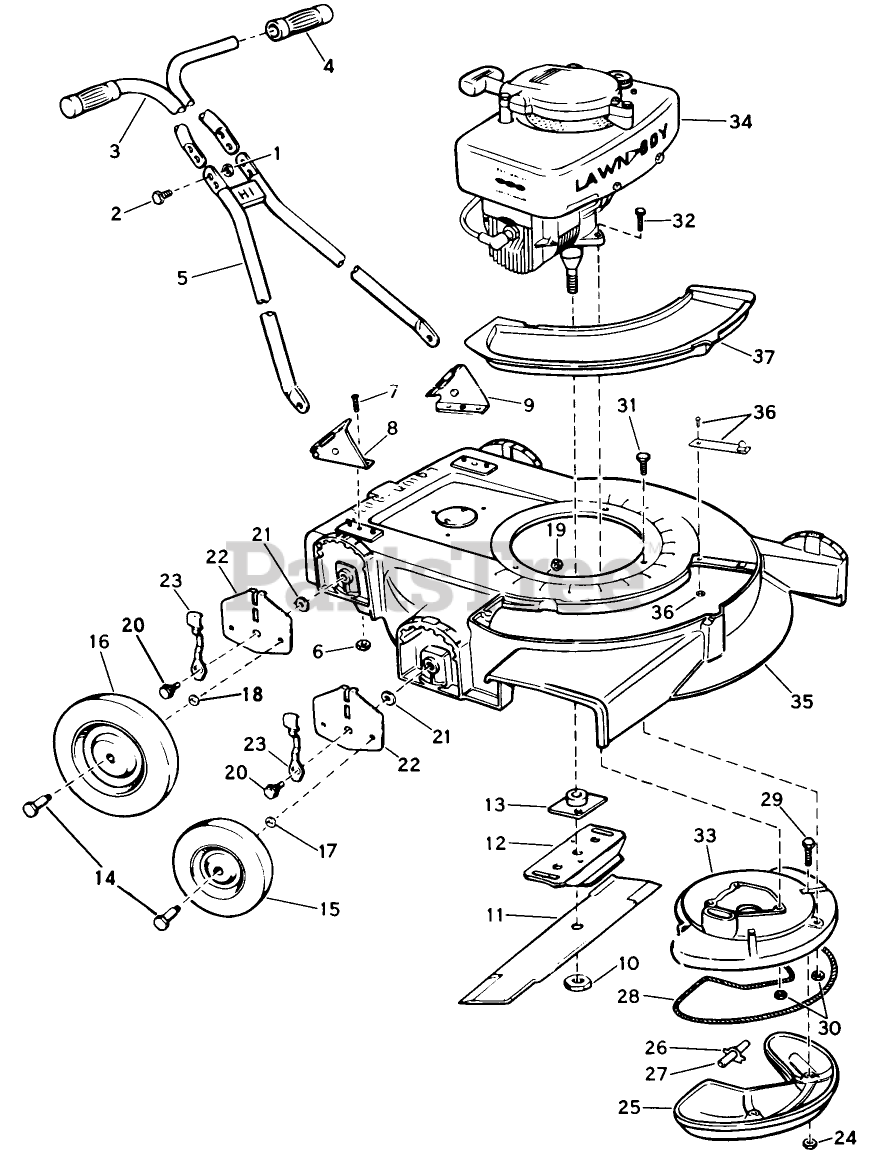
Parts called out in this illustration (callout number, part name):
1	STOP NUT
4	HANDLE GRIP
10	NUT-BLADE
13	PLATE AND COLLAR ASM
14	BOLT WHEEL
17	WASHER WROUGHT
18	WASHER WROUGHT
24	LOCKNUT E
26	Gasket-Internal Tube
27	Tube-Internal Muffler
35	Housing Cover Assy. 19"
36	Spring, Rivet Washer Assy.
